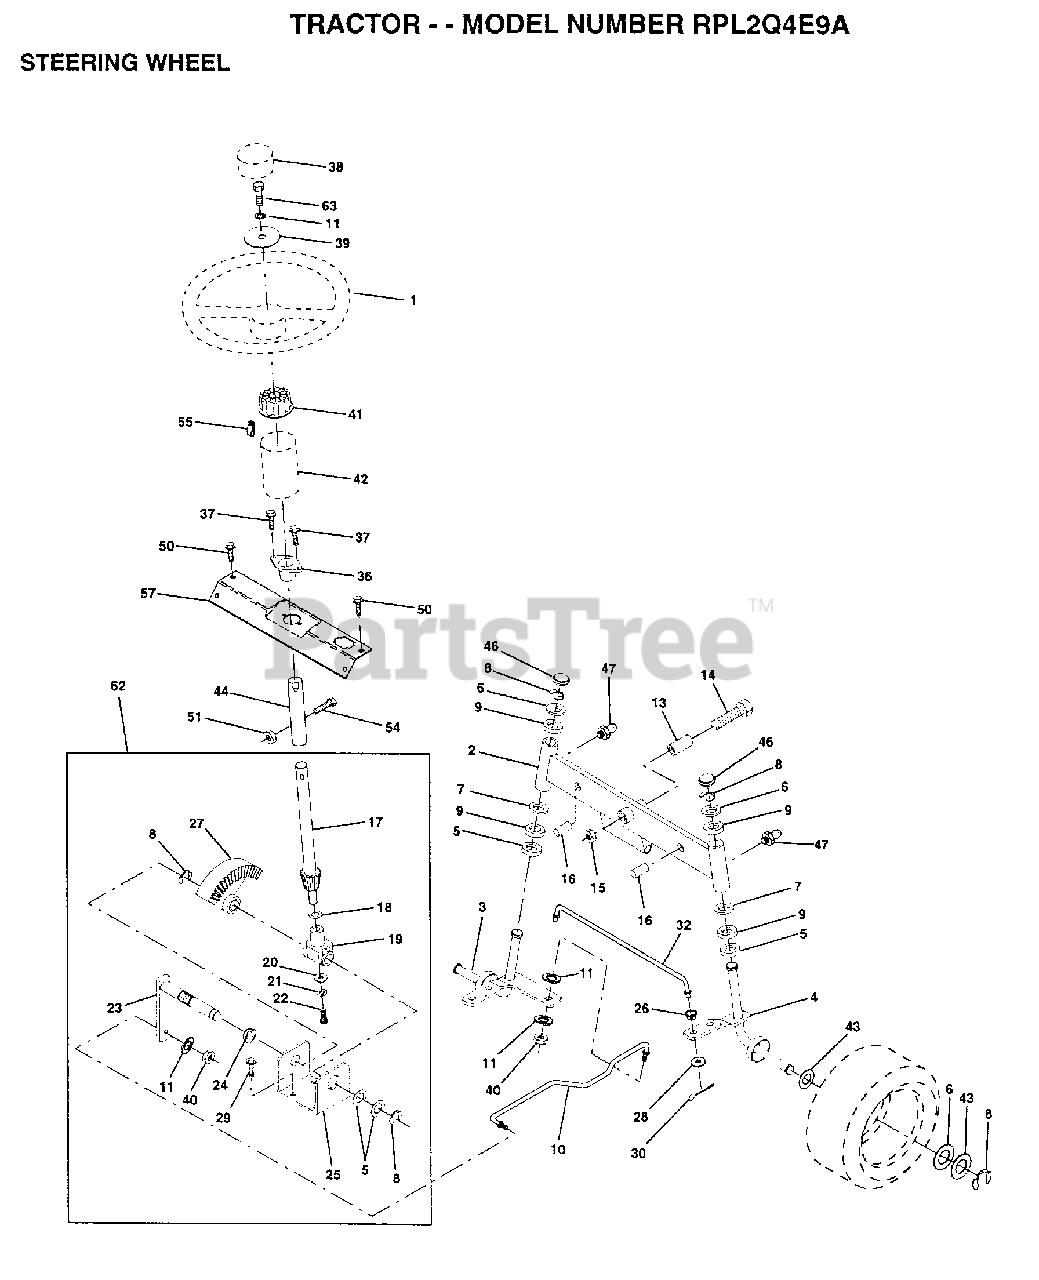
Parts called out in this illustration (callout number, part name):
2	AXLE ASM FRONT
3	SPINDLE LH
4	SPINDLE RH
5	WASHER .T
6	WASHER
7	WASHER
8	RING
9	COL. SRTG. BEAR.
11	LOCKWASHER
13	BEARING
14	BOLT HEX 5/8-11
15	"NUT-LOC,FLANGE LT"
16	AXLE PIN
17	SHAFT ASM STEERIN
18	THRUST WASHER
19	SUPPORT.SHAFT
21	LOCKWASHER
22	SCREW.SCKTHD.CAP
24	NYLINER T
25	"BRKT,STEERING"
26	BUSHING.DRAGLINK
27	GEAR SECTOR
28	WASHER
29	SCREW
30	COTTER PIN
32	TIE ROD
37	"SCREW-TT,10-32 FL"
38	ST WHL INSERT CAP
39	WASHER T
40	GRIPCO NUT
41	ADAPTER LT
42	BOOT SHAFT STEER
43	WASHER
44	SHAFT EXT STEERIN
46	CAP
47	ZERK M
50	SCREW HEX CRT
51	NUT
54	BOLT
57	SUPPORT SHAFT STR
63	BOLT
